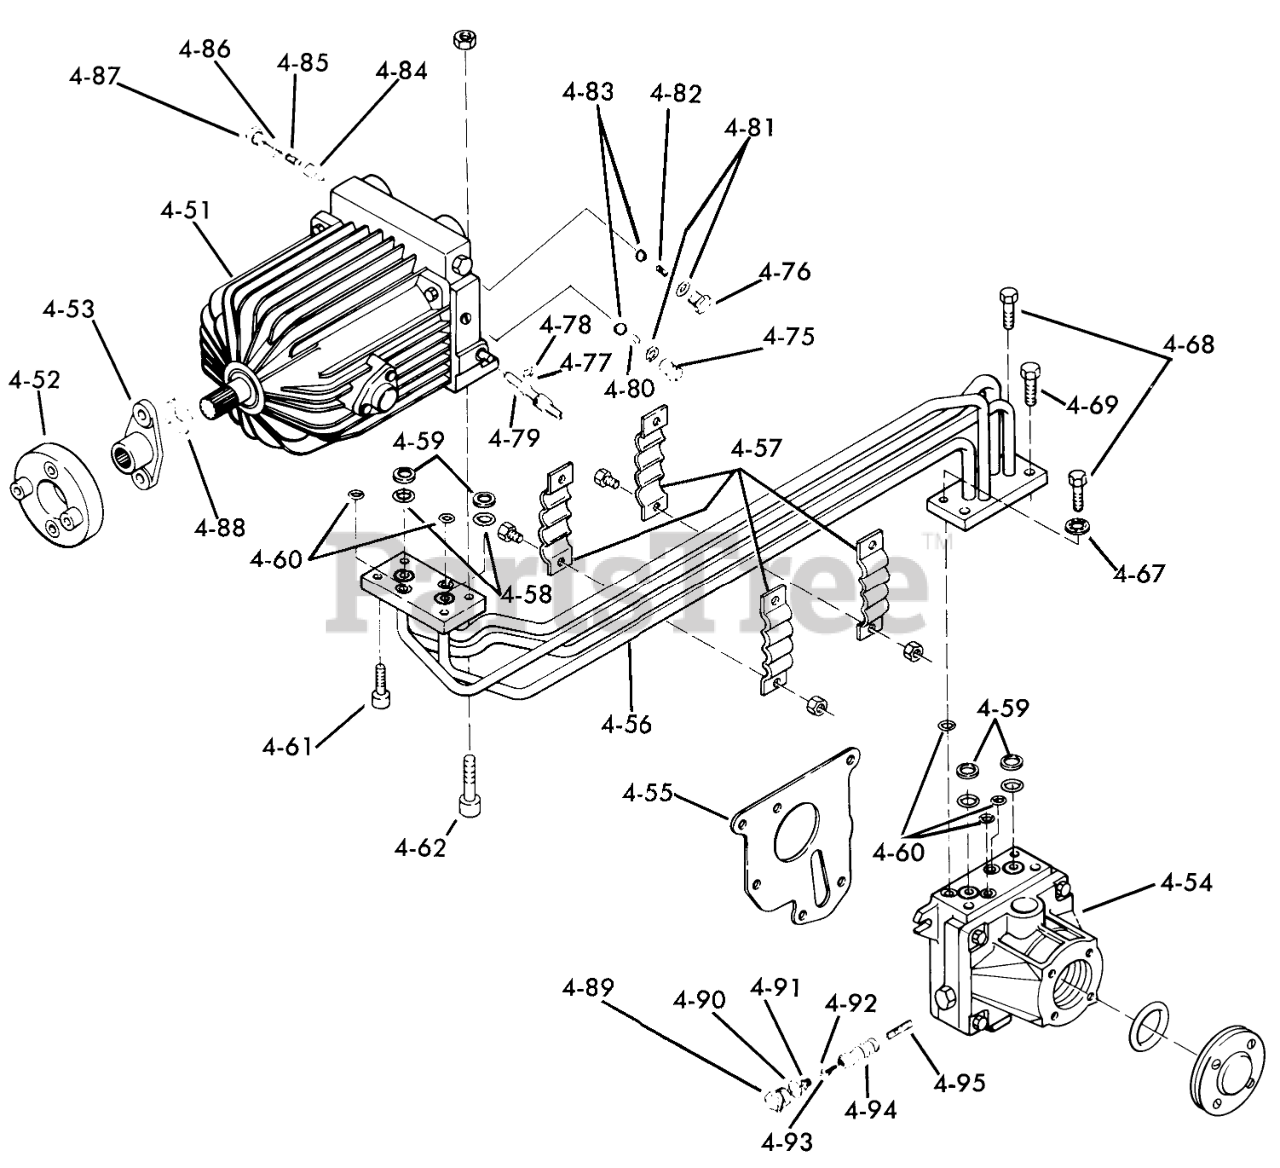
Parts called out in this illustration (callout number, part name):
4-51	SRV BULLT 437B
4-54	SRV BULLT 437B
4-55	GASKET
4-58	O RING
4-59	RING BACKUP
4-60	O RING
4-78	O-RING
4-81	O RING
4-86	O RING
4-97	O-RING
